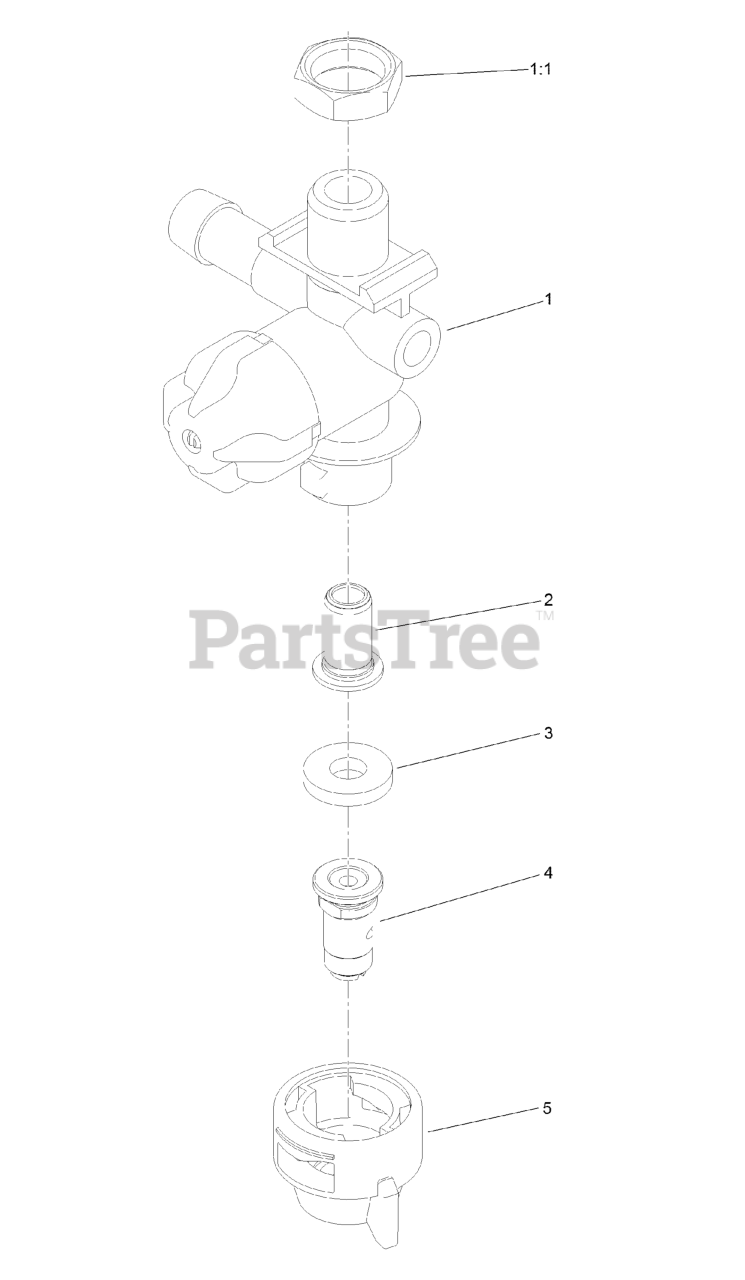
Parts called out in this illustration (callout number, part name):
1	RH NOZZLE BODY ASM
1:1	NUT-NYLON
2	STRAINER-TIP
4	NOZZLE-SPRAY, WHITE
5	CAP-NOZZLE
